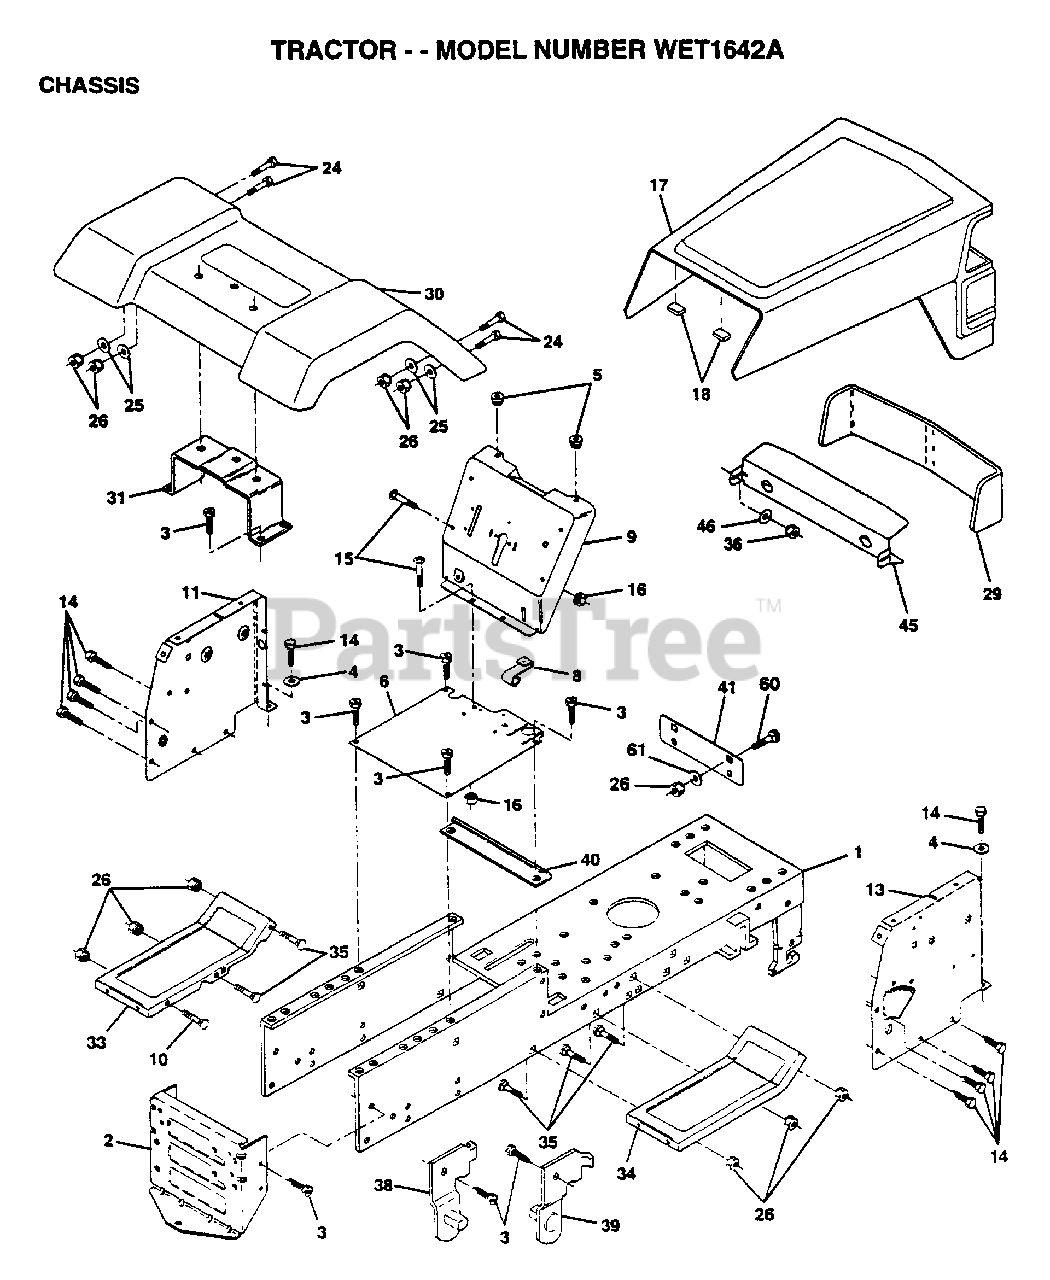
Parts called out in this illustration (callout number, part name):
1	CHASSIS.WLD.11GA
3	SCREW
4	WASHER
8	"CLIP,INSULATOR"
9	DASH.SLKSCRN.1PC.
11	PANEL.DASH.LH.
14	SCREW LT
15	SCREW
17	HOOD/GRILLE.ASM.
24	BOLT
25	WASHER
26	NUT
31	BRACKET SUPT FEND
33	FOOTREST.LH.LT/GT
34	FOOTREST.RH.LT/GT
35	BOLT
36	PAL NUT LT
38	BRACKET ASM LH
39	BRACKET ASM RH
40	SPACER FENDER LT
41	PLATE EXTEN FEND
46	RETAINER
60	BOLT
61	WASHER
